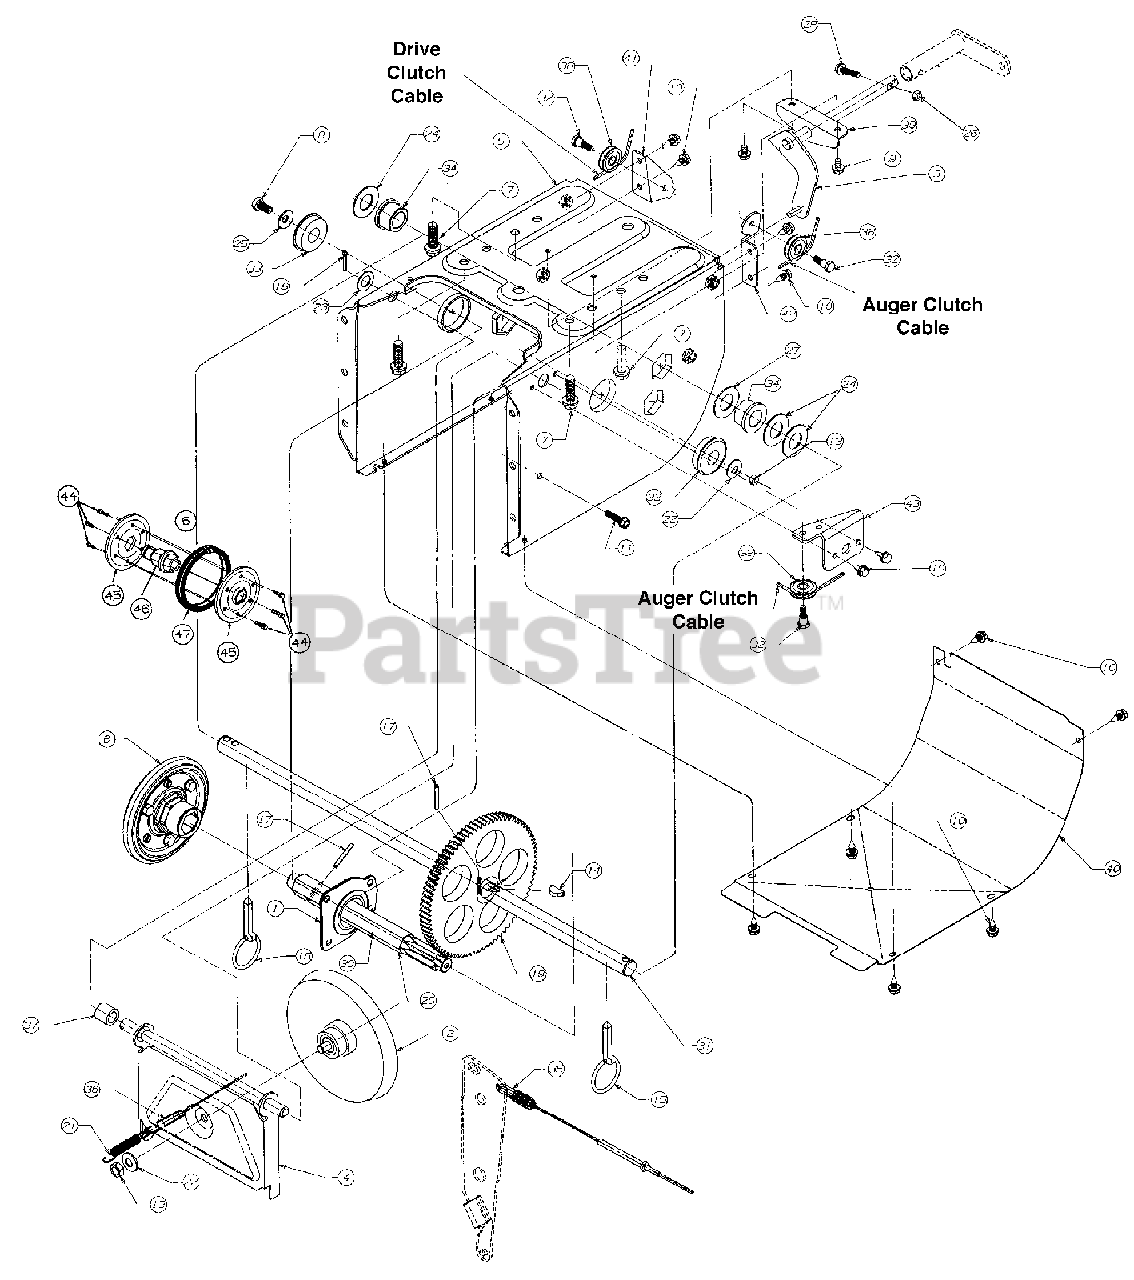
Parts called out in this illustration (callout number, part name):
1	Bearing Ass'y.
2	Ass'y., Friction Wheel Disc
3	Rod Shift, Wheel Drive
7	Hex Self-Tap Screw
8	Hex Hd. Cap Screw
9	Scr., Hex Wash.
10	Hex Self-Tap Scr.
11	Screw, Hex
13	Nut, Hex
15	Pin, Klick
16	Pin, Cotter
17	Pin, Roll
20	Shaft, Hex
21	Extension Spring
22	Washer, Bell
23	Flat Washer
24	Washer, Flat
25	Washer, Bell
26	Nut, Top lock
27	Washer, Flat
28	Hex Screw
31	Axle .750 x 22.2
31	Axle .750 x 24.5
32	Screw, Shoulder
33	Bearing, Ball
34	Flange Bearing
35	Cable, Auger
36	Cable, Clutch
37	Spacer
38	Roller, Cable
45	Friction Plate
46	Friction Wheel Hub
47	Friction Wheel Rubber
